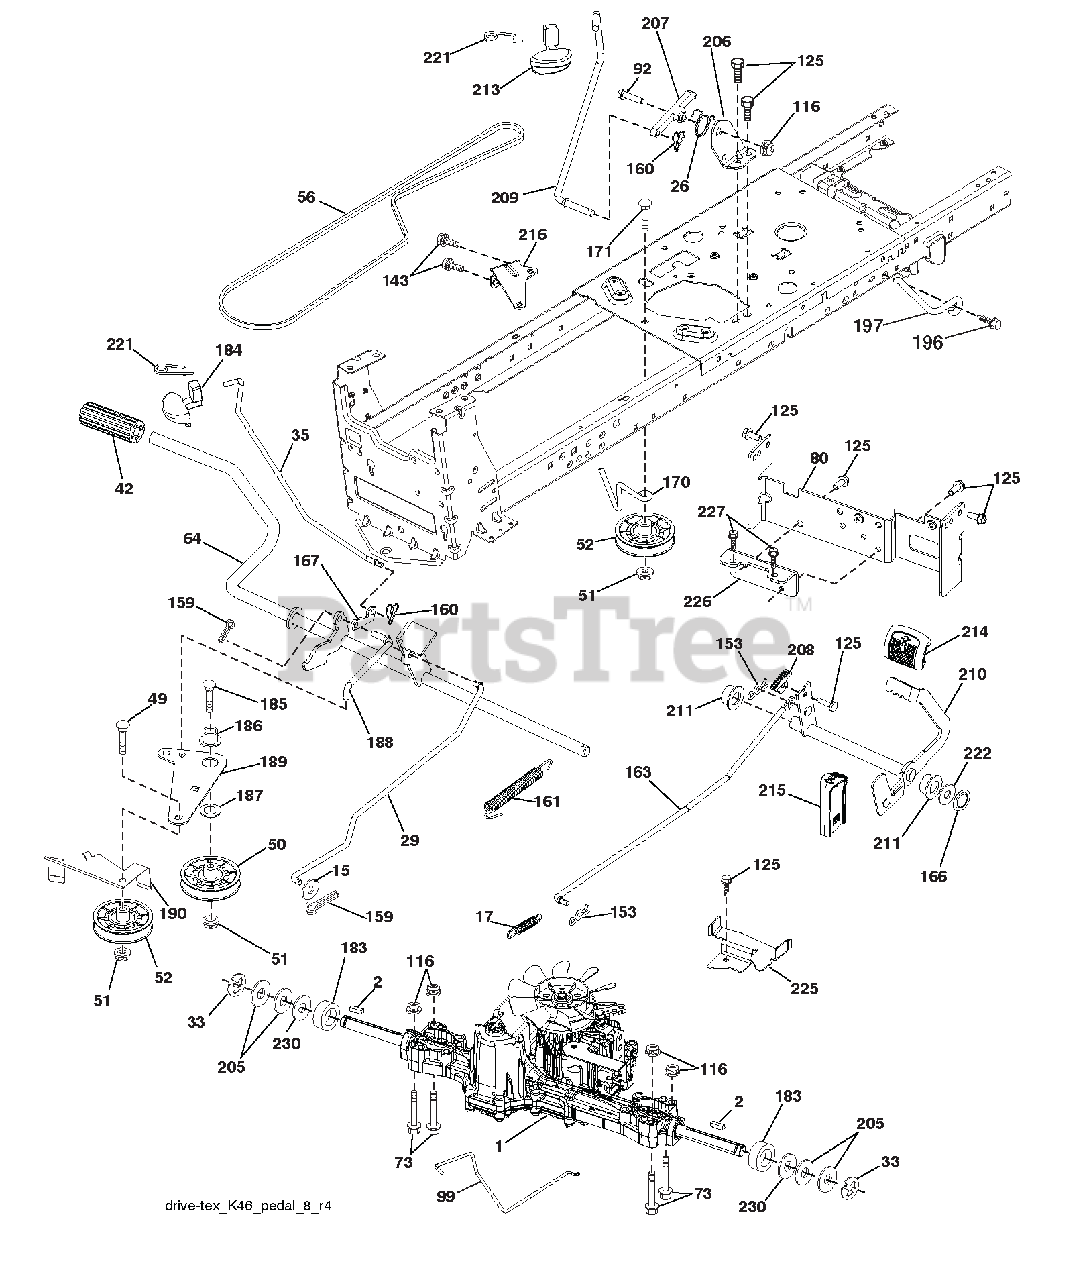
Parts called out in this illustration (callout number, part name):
2	KEY.SQUARE.2.0 X .1845/.1865
15	WASHER.13/32 X 13/16 X 16 GA.
17	SPRING.BRAKE.K46.GREEN
26	SPRING.RETURN.CRUISE
29	ROD.BRAKE.K46
33	E-RING.#5133-75
35	ROD.BRAKE.PARKING.LT.TEX
42	COVER PEDAL BLK ROUND
49	BOLT.RDHD.3/8-16UNCX1-3/4.GR5
50	IDLER.FLAT.910"OFFSET
51	Nut, Hex, Flangelock 3/8-16
52	IDLER.V-GROOVE.910"OFFSET
56	V-BELT.MOWER.92.40.42/K46
64	SHAFT ASM.PEDAL.BRK.CNTRL.PCH
73	BOLT.HEX.FLGHD.5/16-18.GR.5
80	STRAP.TORQUE.K46/18"TEX
92	Bolt, Hex Head 5/16-18 x 1-1/4
99	ROD BYPASS
116	Nut, Lock Hex Flange 5/16-18 u
125	SCREW.5/16-18X3/4.SMGML.TAP/BL
143	SCREW.THDROL.5/16-18 X 1/2TYTT
153	RETAINER SPRING
159	PIN.COTTER.1/8 X 3/4.CAD.
160	RETAINER.CLIP(M).DIA.290
161	SPRING.RETURN.CLUTCH.6.75
163	ROD CONTROL
166	NUT PUSH .625
167	LATCH.BRAKE.PARKING
170	KEEPER BELT CENTERSPAN
171	BOLT.RD.HD.SQ.NK.3/8-16UNC X 2
183	SPACER.AXLE.HYDRO/PEERLES
184	HANDLE.PARKNG.BRAKE.LT.TEX.667
185	BOLT.RDHD.3/8-16UNC X2-3/4 GR5
186	SPACER.RETAINER
187	WASHER.13/32 X 2 X 10 GA.
188	LINK.CLUTCH.GROUND DRIVE
189	BELLCRANK.GROUNDRIVE.NSTG/NSTL
190	KEEPER.BELLCRANK.DRIVE.GROUND
196	SCREW.3/8-16X1.SMGML.TAP/R.BLK
197	LINK CLUTCH ANTI-ROTATION
205	WASHER.25/32 X 1-5/8 X 16GA.
206	BRACKET.MOUNT.LATCH.CRUISE
207	LATCH.CONTROL.CRUISE
208	GEAR SECTOR.CONTROL.CRUISE
209	ROD CONTROL CRUISE
210	ROCKER ASM.PEDAL CONTROL.TEXLT
211	BEARING.NYLON.BLK..629 ID.
213	KNOB.CONTROL.CRUISE
214	PAD PEDAL FORWARD
215	PEDAL REVERSE
216	BRACKET.PULLEY.IDLER.WTEX
221	RETAINER.SPRING.CLIP.HANDLE
222	WASHER.21/32X1-1/4.10GA.N/PLTD
225	KEEPER.BELT.TRANSAXLE.K46
226	BRACKET.MOUNT.TORQUE.K46.TLT
227	SCREW 5/16-18 X 3/4
230	WASHER.HARDEN..793 X 1.637X060
